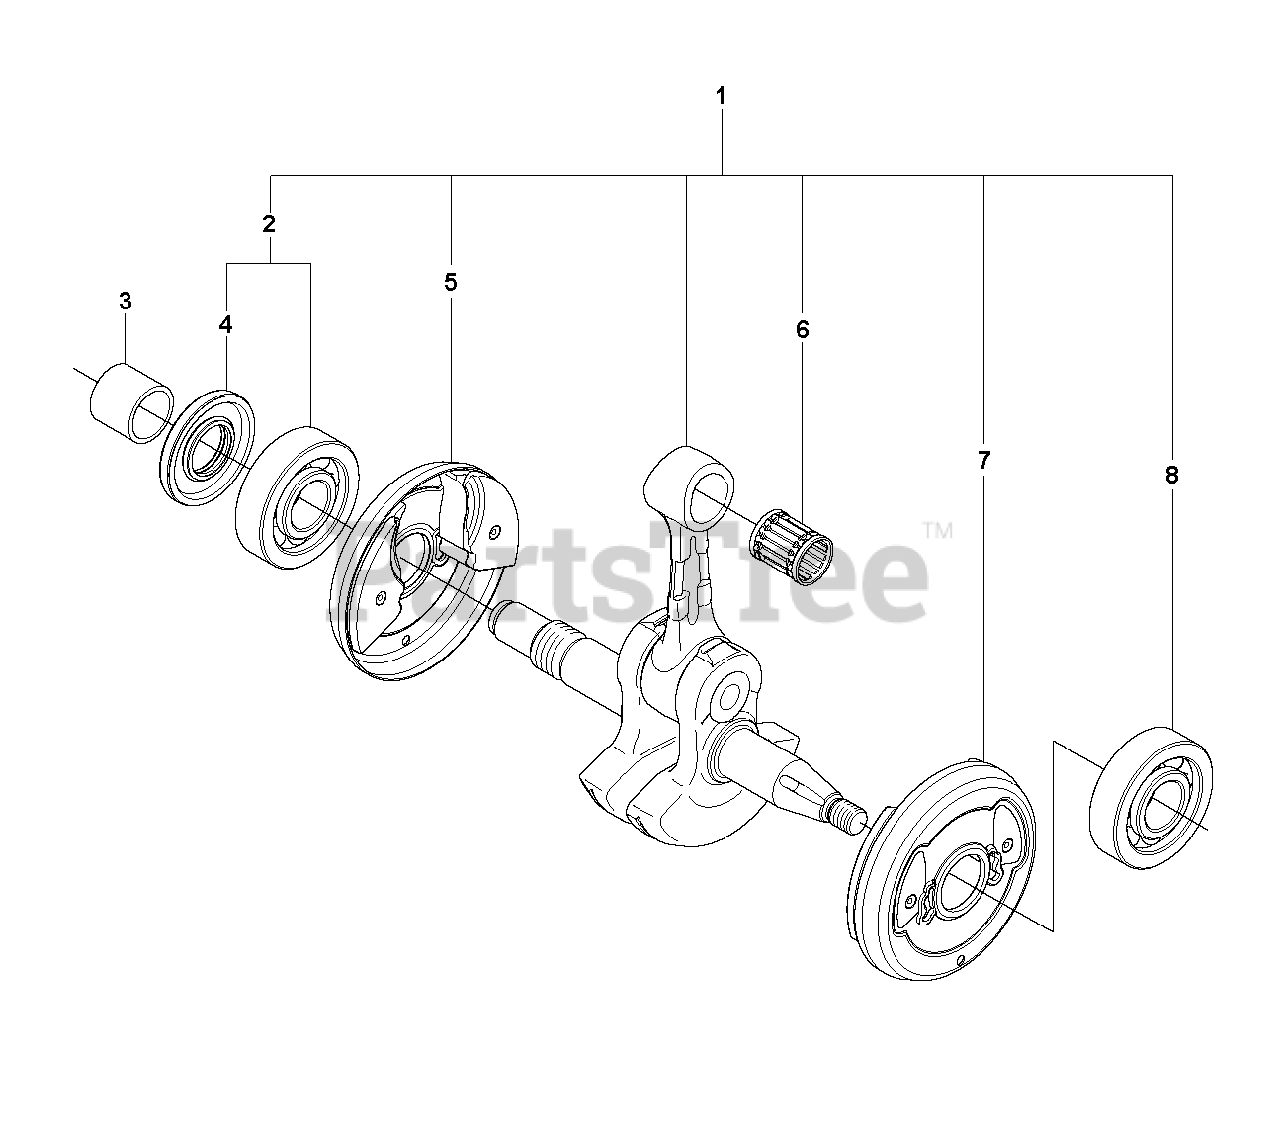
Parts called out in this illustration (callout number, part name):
1	RP CRANKSHAFT ASSY
2	BALL BEARING
4	RADIAL SEAL
5	CUP
6	SUPPORT BUSHING
7	CUP
8	BALL BEARING
